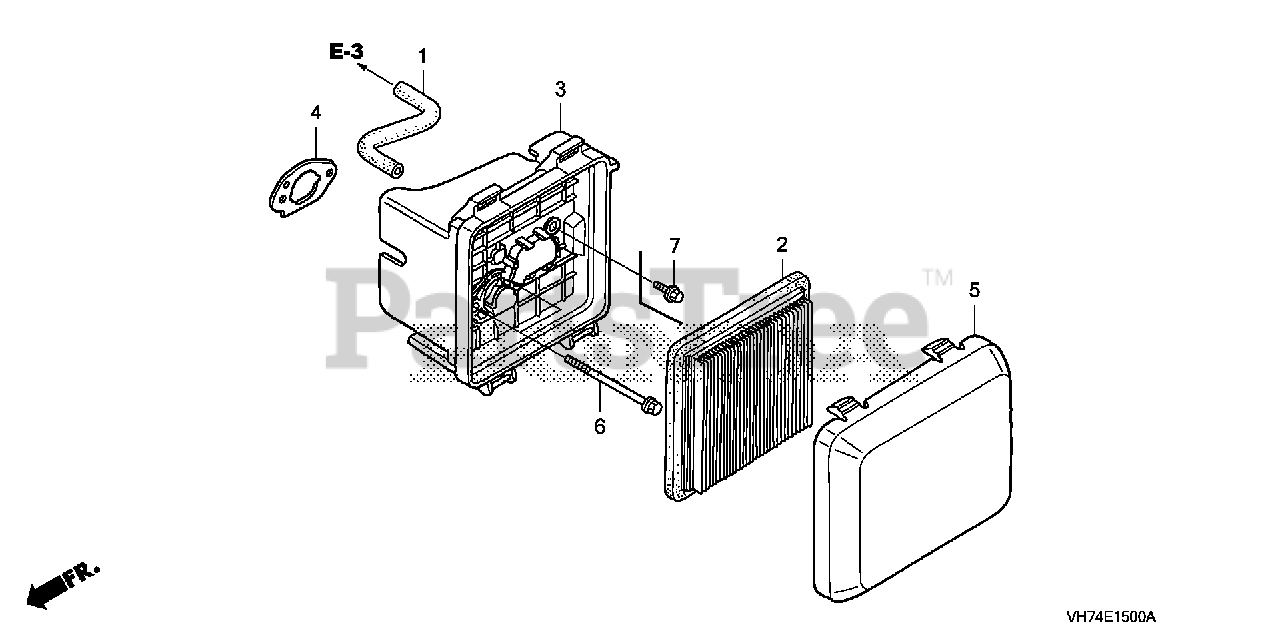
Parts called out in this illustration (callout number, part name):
1	TUBE, BREATHER
2	ELEMENT, AIR CLEANER (WIX FILTERS)
3	CASE ASSY., AIR CLEANER
4	GASKET, AIR CLEANER
5	COVER, AIR CLEANER
6	BOLT, SPECIAL (6MM)
